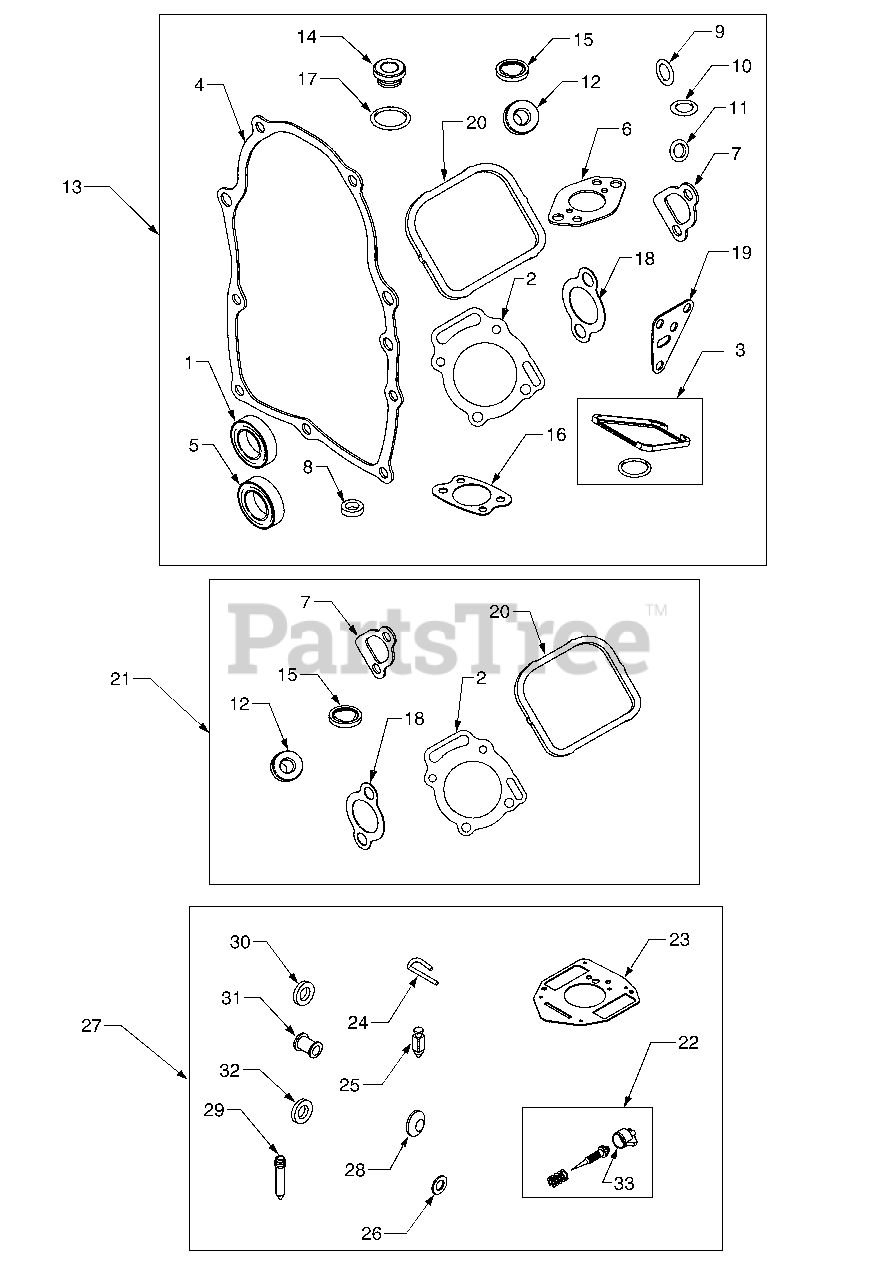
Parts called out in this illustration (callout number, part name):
1	Seal, Oil
2	Gasket, Cylinder Head
3	Gasket, Breather
4	Gasket, Crankcase
5	Seal, Oil
6	Gasket, Intake
7	Gasket, Intake
8	Seal, Governor Shaft
9	Seal, O-Ring (Crankcase Cover)
10	Seal, O-Ring (Oil Pump)
11	Seal, O-Ring (Oil Pump Screen)
12	Washer
13	Gasket Set
14	Seal, Fill Tube
15	Seal, Fill Plug
16	Gasket, Air Cleaner
17	Seal, O-ring
18	Gasket, Exhaust
19	Gasket, Filter Adapter
20	Gasket, Rocker Cover
21	Overhaul Kit, Valve
22	Valve, Idle Adjust
23	Gasket, Carburetor Body
24	Pin, Float Hinge
25	Valve, Fuel Inlet
27	Overhaul Kit, Carburetor
28	Plug, Welch
29	Nozzle, Carburetor
30	Collar, Throttle
31	Collar, Choke
32	Seal, Shaft
33	Cap, Limiter
